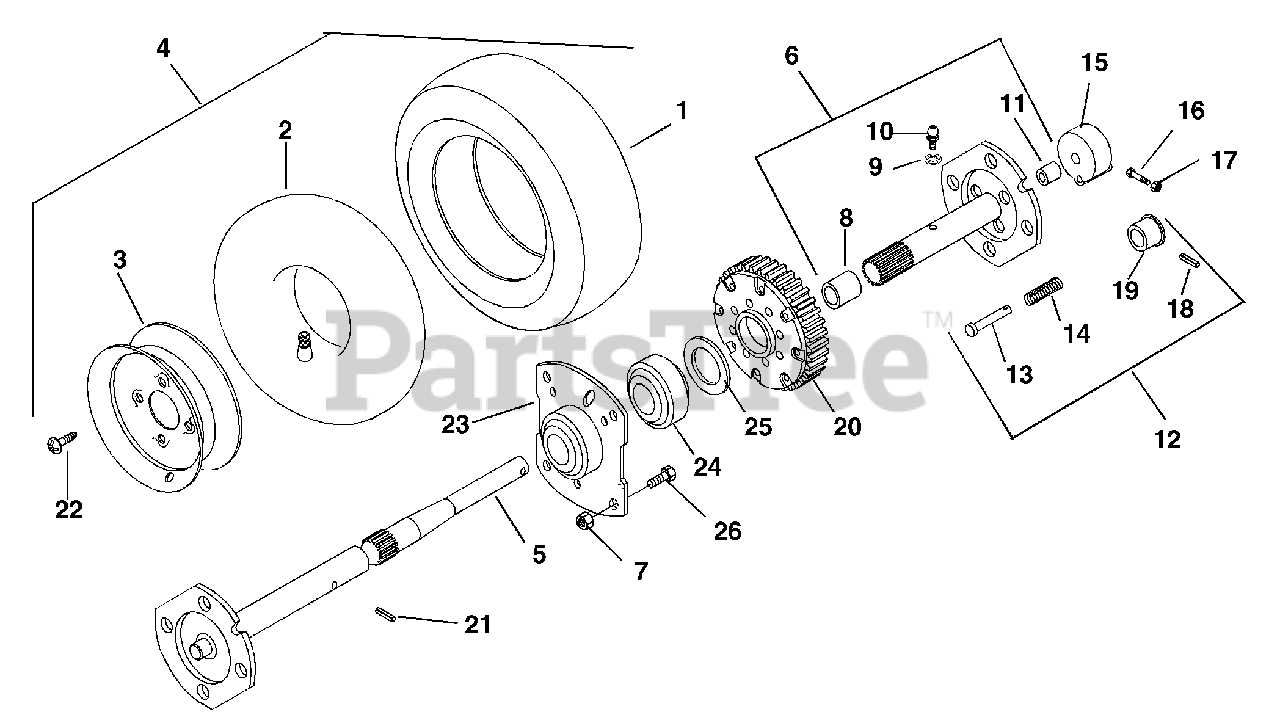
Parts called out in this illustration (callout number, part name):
1	TIRE 4.80-8 NHS
4	T/WHL ASSY 4.80-8
5	AXLE, RH
6	L.H.AXLE ASSEMBLY
7	@NUT-SPNLK-FLG .25-20 YWZC
8	BSHG-SLV .750X.814X .750 BRZ
9	WSHR-LK .250X.047 LT YWZC
10	FTG-LUBE .25-28X.256 YWZC
11	BSHG-SLV .562X.625X.625 BRZ
12	LOCKOUT HUB ASSEMBLY
14	SG-COMP .028X.34X1.062 WLD75
15	LOCKOUT HUB
16	BLT-HEX .25-20X2.0 PL GR8 YWZC
17	NUT-JAM-NYL .250-20 W/INSERTYZ
18	PIN-ROLL .093X1.00
20	DIFFERENTIAL ASSEMBLY
21	PIN-ROLL .188X1.50
22	SCR-TAP .500-20X.62 HH YWZC
23	BEARING RETAINER
24	BRG-BALL 1.13X2.19X.63
25	WSHR-FL-STL 1.140X1.718X.134YZ
26	BLT-SERNK SL .25-20X.50 YWZC
